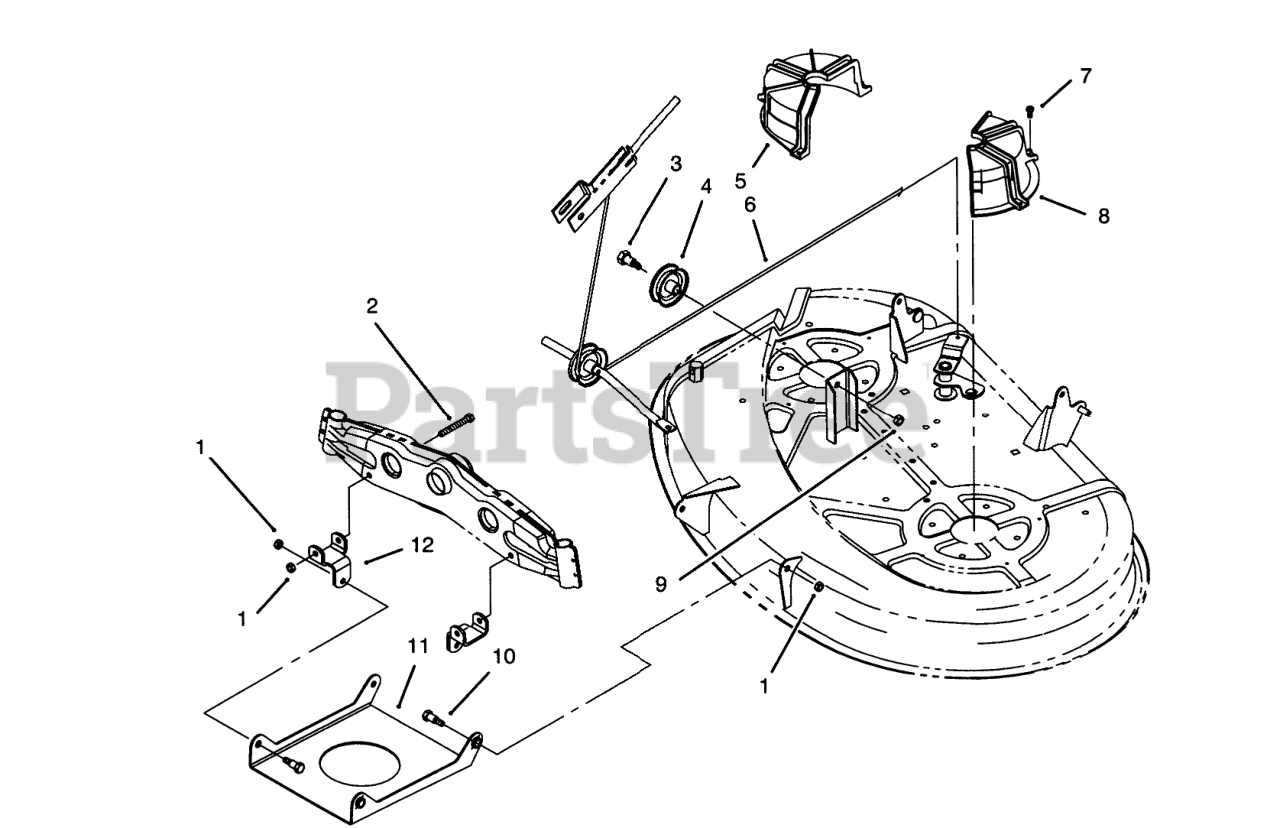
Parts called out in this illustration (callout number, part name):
1	NUT-LOCK, NI
2	SCREW-HH
3	SCREW-SHOULDER, HH
4	PULLEY, CABLE
5	GUIDE-BELT, RH
6	DECK ENGAGE CABLE
7	SCREW-HWHTF
8	GUIDE-BELT, LH
9	NUT-LOCK, NI
10	BOLT-SHOULDER
11	Pan-Front Deck Suspension
12	Bracket-Deck Suspension
